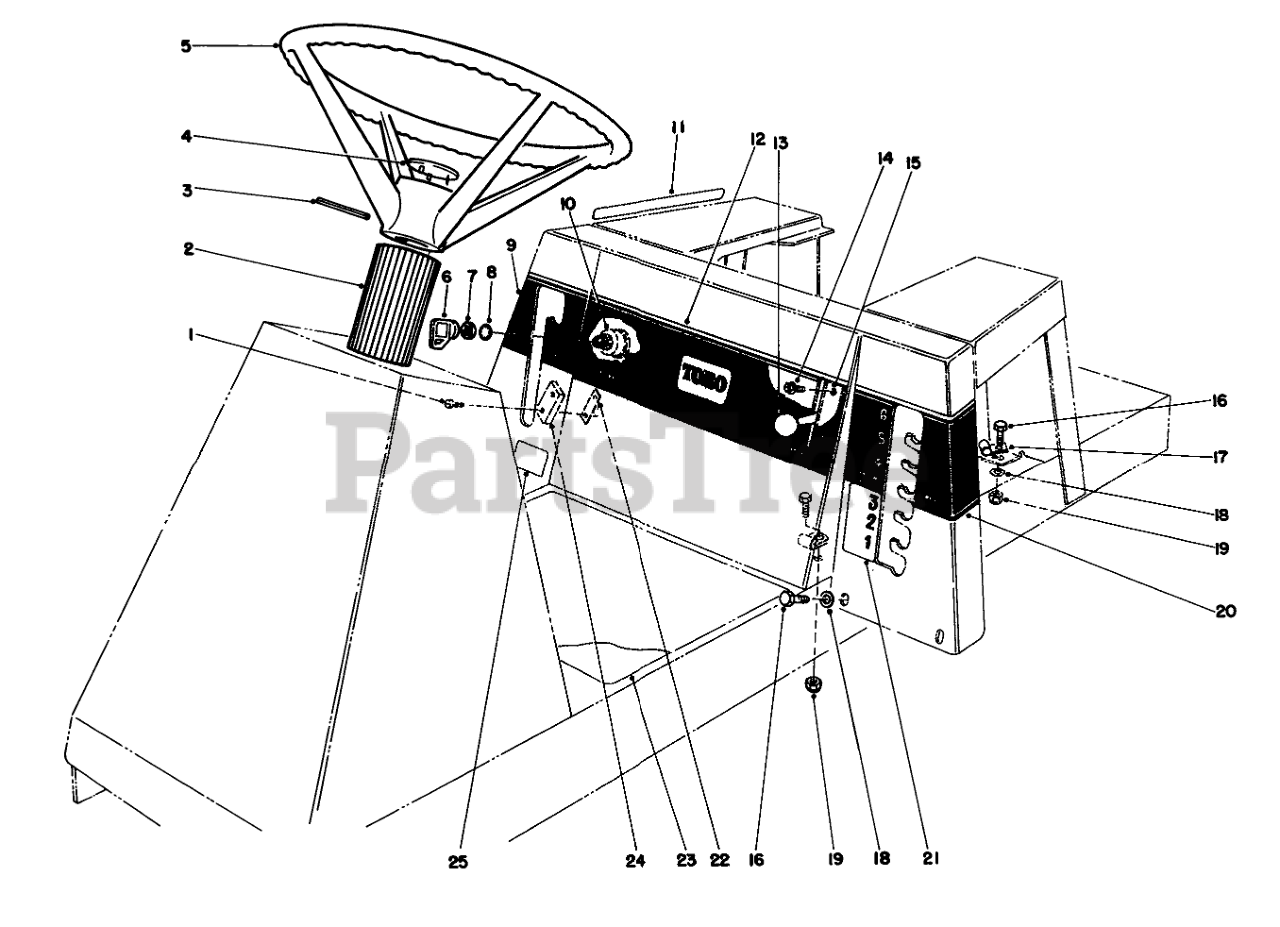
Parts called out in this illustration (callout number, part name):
1	SCREW-SPH
2	COVER-STEERING SHAFT
3	PIN-ROLL
4	STEERING WHEEL INSERT
5	Assy.-Wheel, Steering (Incl. Ref. #4)
6	KEY-IGNITION
7	NUT-HH
8	WASHER-TOOTH, INTERNAL
9	DECAL-UPPER DECK ENGAGE
10	Switch-Ignition (Incl. Ref. #6-8)
11	DECAL - SHIFT PATTERN
12	DECAL-FRT SEAT CONTROLS
13	KNOB-CONTROL
14	SCREW-HWHTF
15	Control-Throttle (Incl. Ref. #13)
16	SCREW-HH
17	CLAMP
18	WASHER-PLAIN
19	NUT-LOCK, NI
20	DECAL - UPPER HOC
21	DECAL - LOWER HOC
22	NUT-SPEED
23	INSTRUCTION DECAL
24	SWITCH-MICRO
25	DECAL-LOWER DECK ENGAGE
